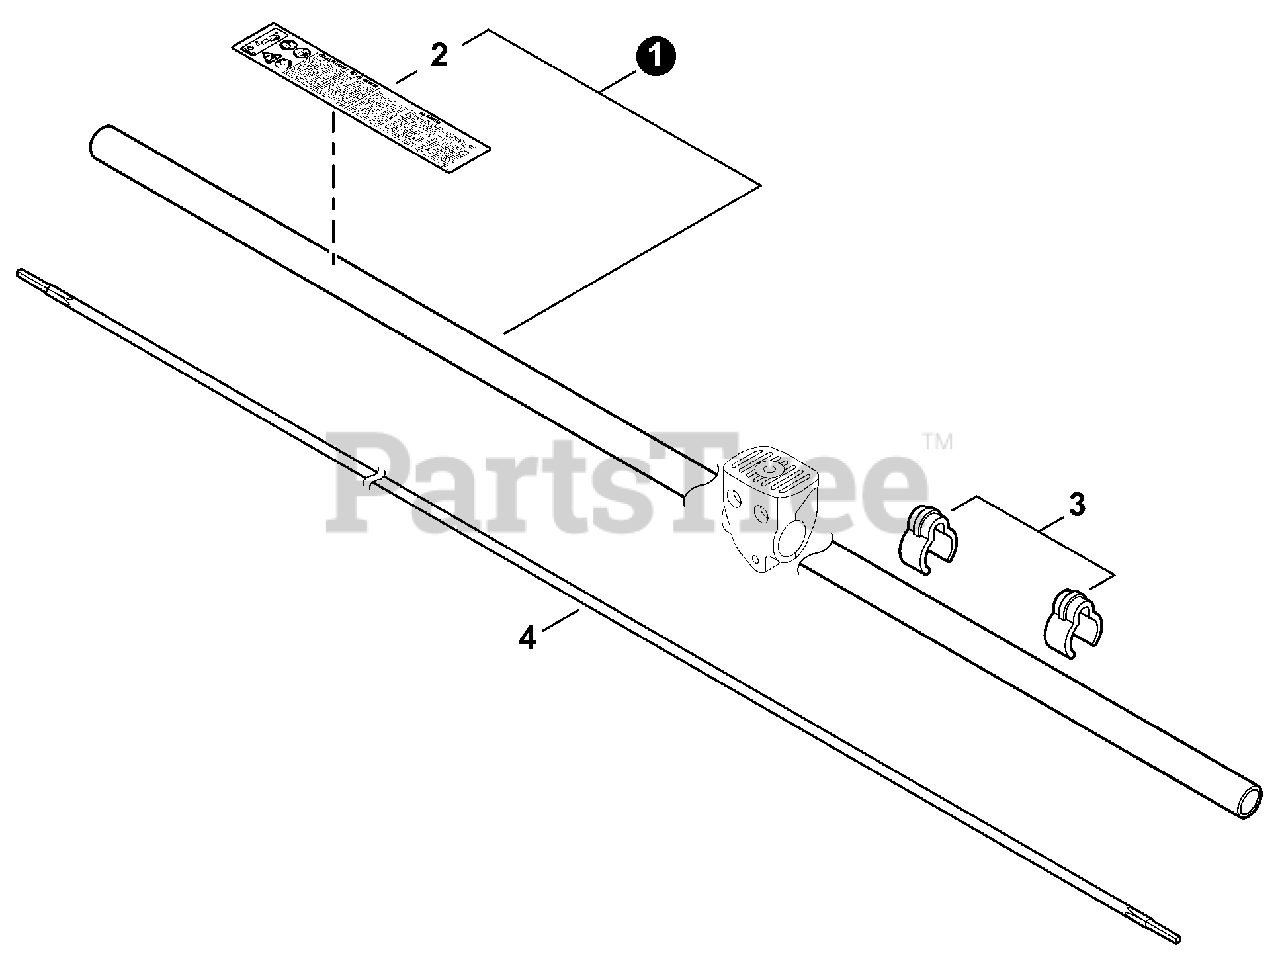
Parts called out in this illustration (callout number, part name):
1	MAIN PIPE ASSY
2	LABEL, CAUTION
3	CLIP, CABLE 25 MM
4	DRIVESHAFT - FLEXIBLE
